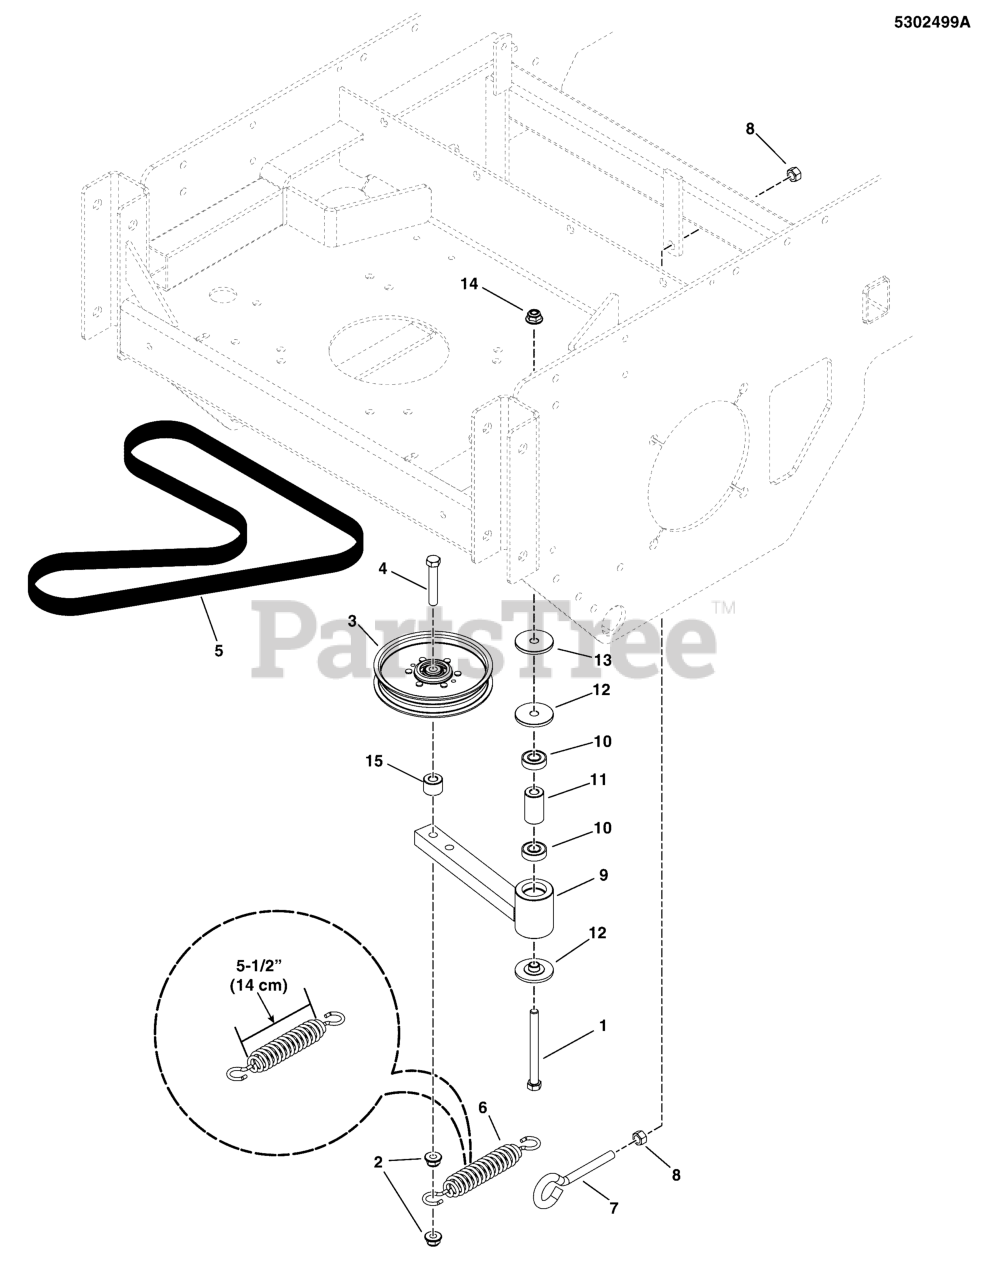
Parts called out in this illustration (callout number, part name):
1	BOLT, 1/2-13 X 3-1/2, HEX HD, GD5, CZ (SV)
2	NUT, 3/8-16 HEX NYLOCK FLANGE
3	PULLEY-IDLER 04.00 OD 0.378ID 1.06 W/ BRG
4	BOLT, 3/8-16 X 2-3/4" GD5 CZ
5	BELT, HB, 65.1"EL
6	SPRING-EXT, 1.04 ODX6.935LGX.148WR, BLK
7	EYE BOLT, 3/8-16 X 5, 2.88THRD, 1EYE, CZ
8	NUT, 3/8-16 HEX
9	ASSM, IDLER ARM, PUMP DRIVE, 1/2ID, CAST
10	BEARING, BALL, AXLE
11	SPACER, .52 X .84 X 1.53, PM
12	SPACER, IDLER ARM, 1/2, PM
13	WASHER, .52 X 1.75 X .14, CZ
14	NUT, Hex Flange, Nylock, 1/2-13
15	SPACER-0.390ID 0.90 OD 0.34 LG P'MTL YEL
